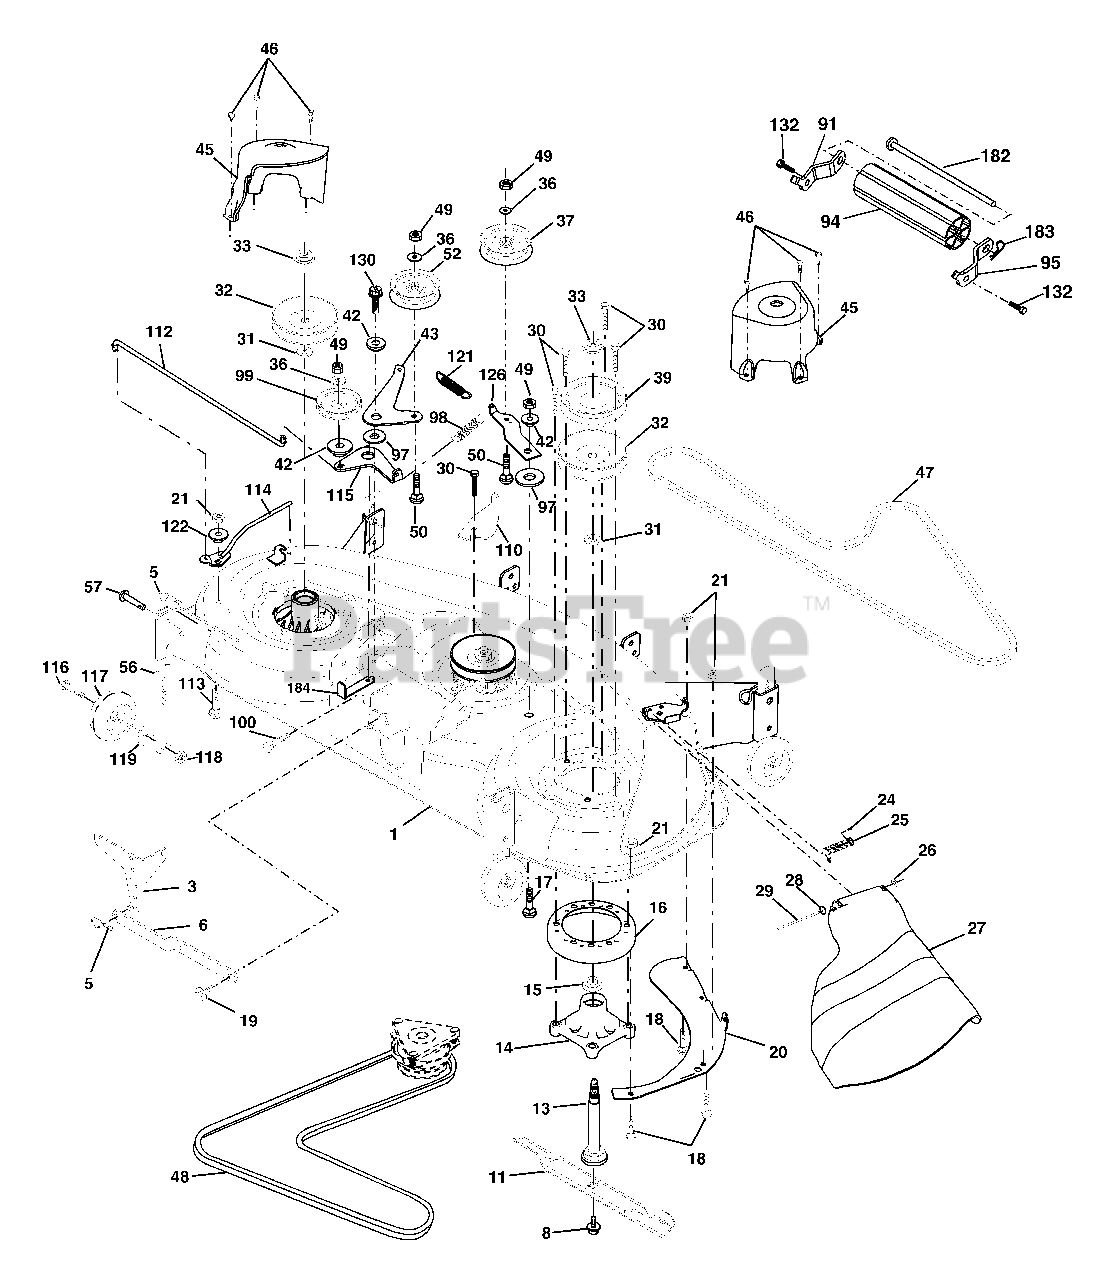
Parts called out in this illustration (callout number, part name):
1	Deck Weldment Mower 48
3	Bracket Asm., Sway Bar
5	Retainer Spring
6	Sway Bar Deck
8	Bolt 7/16 Asm. Blade
13	Shaft Asm. w/Lower Bearing
14	Mandrel Asm.
15	Bearing, Ball, Mandrel
16	Stripper Mandrel Deck
17	Bolt RDHD Sq Neck 3/8-16 x 1.25
18	Bolt, Carriage 5/16-18 x 5/8
19	Bolt, Hex Hd, Shoulder 5/16-18
20	Baffle, Vortex Mower
21	Nut, Crownlock 5/16-18 UNC
24	Cap, Sleeve
25	Spring, Torsion
27	Deflector Shield
28	Washer 11/32 x 5/8 x 16 Ga.
29	Rod, Hinge
30	Screw, Thdroll Washer Head
31	Washer, Spacer Mower Vented
32	Pulley, Mandrel
33	Nut, Flg. Top Lock Cntr. 9/16
36	Washer 13/32 x 13/16 x 16 Ga.
37	Pulley, Idler, Flat
39	Pulley, Idler, Driven
42	Spacer, Retainer
43	Arm, Idler Secondary
45	Cover, Mandrel Deck
46	Screw, Thdroll. 1/4-20 x 5/8
47	V-Belt, Mower, Secondary
48	V-Belt, Mower, Primary
49	Nut, Crownlock 3/8-16 UNC
50	Bolt, Carr. 3/8-16 x 1-1/2 Gr. 5
52	Pulley Idler Flat
56	Bar Pnt Adj.
57	Pin Head Rivet
91	Bracket Asm N Roller LH
94	Roller Nose 48"
95	Bracket Asm N Roller RH
97	Washer Hardened
98	Spring Primary Drive
99	Pulley Idler "V"
100	Bolt RDHD Sqnk 3/8-16 UNC x 2
107	Baffle Vac Edge Mower
108	Bolt 1/4-20 x 1/2
109	Nut Crownlock 1/4-20
110	Arm Spring Secondary
112	Link Tension Relief Lever
113	Bolt Carr. 5/16-18 x 1
114	Tension Asm. Relief Lever
115	Arm Spring Tension Relief
116	Bolt, Shoulder
117	Gauge Wheel
118	Nut, Centerlock 3/8-16 UNC
119	Washer 3/8 x 7/8 x 14 Ga.
121	Spring Secondary Drive
122	Bushing Pivot Tension Relief
126	Arm, Idler, Primary Deck
130	Screw 3/8-16 x 1.0
132	Screw 3/8-16 x .75
182	Rod Roller Nose
183	Retainer Spring
184	Keeper Belt Idler
